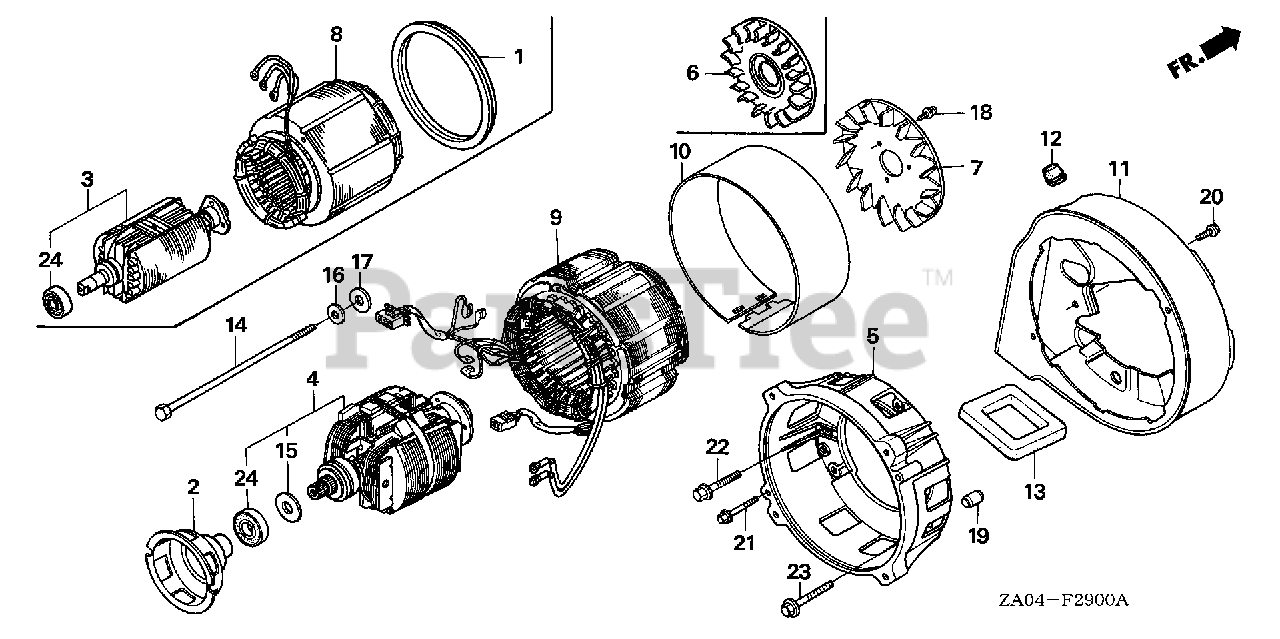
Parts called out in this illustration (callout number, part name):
2	PULLEY, STARTER
4	ROTOR
5	HOUSING, FR. (NOT AVAILABLE)
9	STATOR (NOT AVAILABLE)
10	COVER, STATOR *NH116M* (URBAN SILVER METALLIC)
11	COVER, DUCT (NOT AVAILABLE)
12	GROMMET, DUCT COVER
14	BOLT, HEX. (10X285) (NOT AVAILABLE)
15	WASHER, THRUST
16	WASHER, PLAIN (10MM)
17	WASHER (10.5MM)
18	SCREW, TAPPING (5X14)
18	SCREW-WASHER (5X14)
19	PIN A, DOWEL (10X14)
20	BOLT, FLANGE (6X12)
21	BOLT, FLANGE (6X40)
22	BOLT, FLANGE (8X32)
23	BOLT, FLANGE (8X40)
24	BEARING, RADIAL BALL (6205UU)
